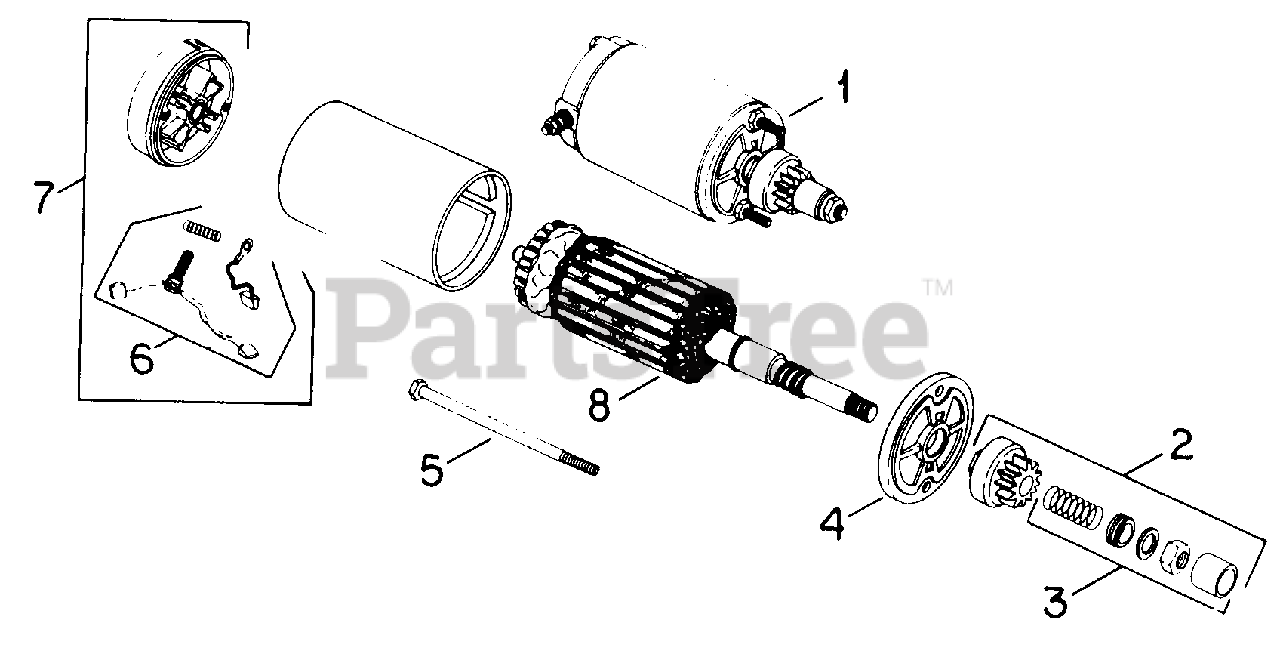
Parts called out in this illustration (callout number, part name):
1	Starter Assy
2	Kit, Drive
3	Kit, Drive Parts
4	Cap, Drive End
6	Kit, Brush & Spring
7	Kit, Commutator End Cap
